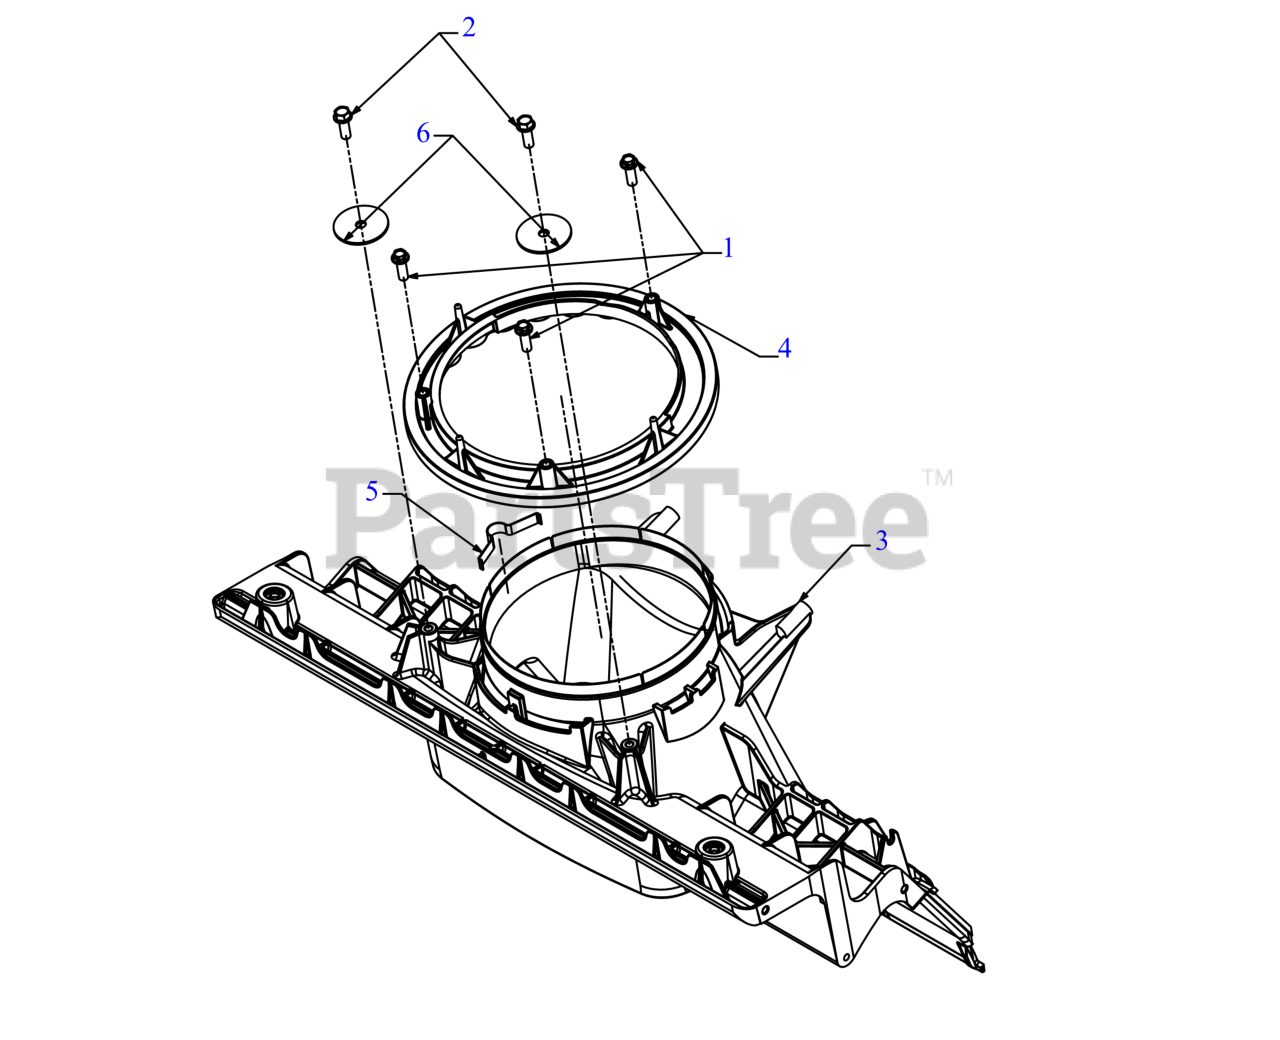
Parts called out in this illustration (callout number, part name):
1	SCREW 1/4 x .750
2	SCREW 1/4-15 x .750
3	CHUTE ADAPTER
4	CHUTE RING
5	CHUTE ADJUSTMENT SPRING
6	FLAT WASHER
